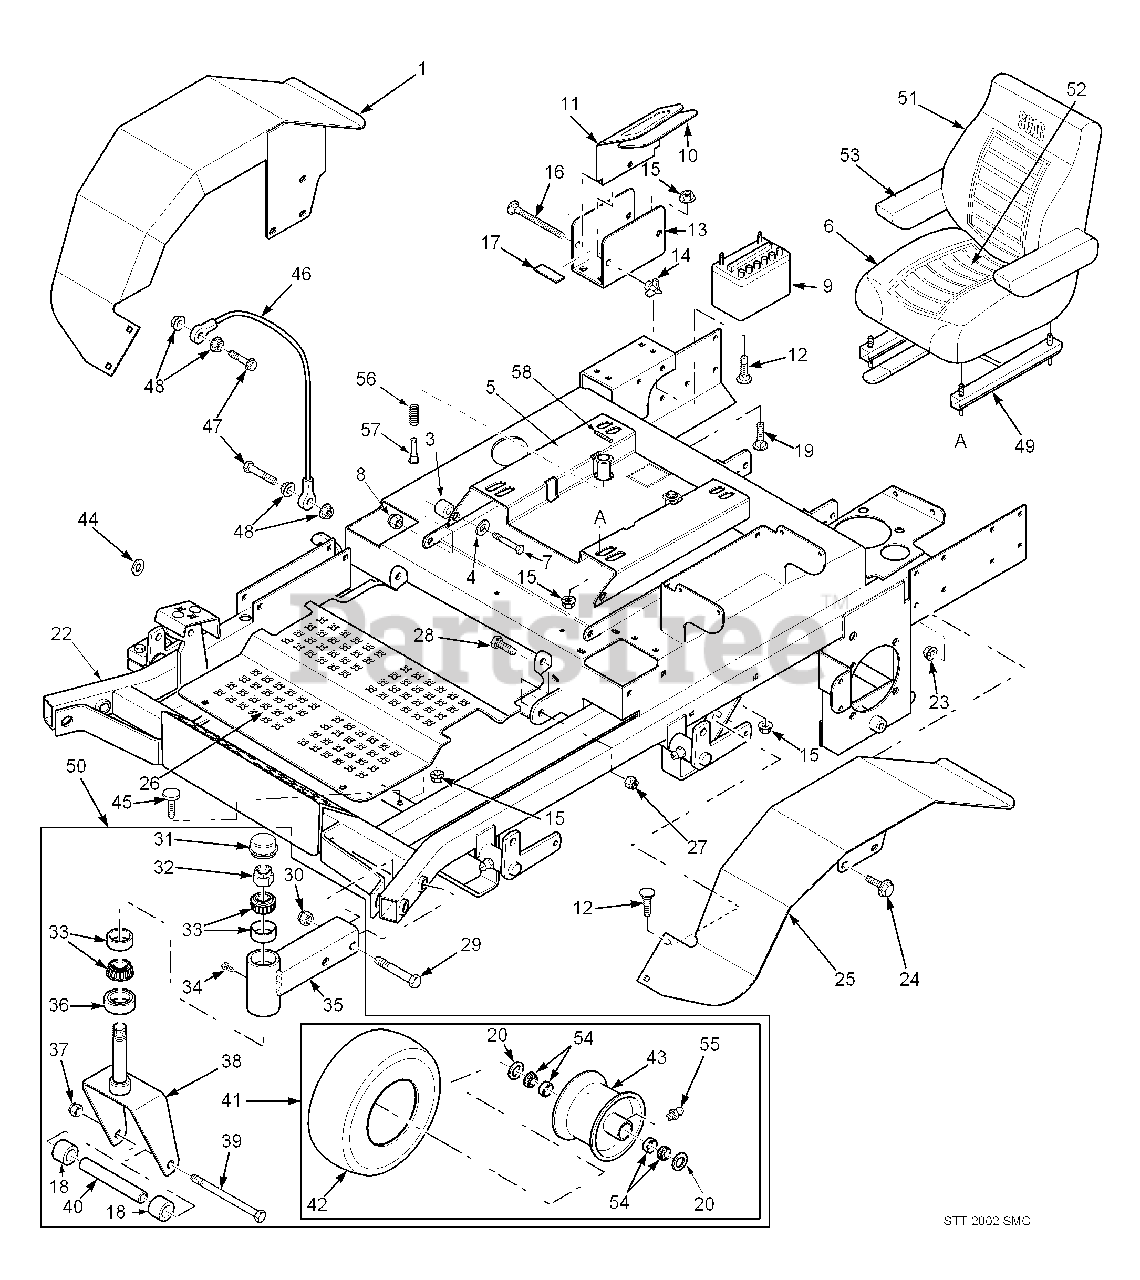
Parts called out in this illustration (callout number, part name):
1	Fender Weldment, RH
2	Bolt, Hex Head, 5/16-18 x 1, Zinc
3	Spacer
4	Flatwasher, 3/8-.391 x .938 x .105
5	Seat Plate Weldment
6	Seat Assembly w/armrest
7	Bolt, Hex Head 3/8-16 x 2.0"
8	Nut, Elastic Stop 3/8-16
9	Battery
10	Pad, Battery Cover
11	Cover, Battery
12	Bolt, Carriage 5/16-18 x 3/4"
13	Plate, Battery Box
14	Wing Nut, 1/4-20 x 3/4"
15	Nut, Hex Serrated Flange 5/16-18
16	Bolt, Carriage 1/4-20 x 6"
17	Rubber Pad
18	Spacer, Caster Wheel
19	Bolt, Carriage 5/16-18 x 1"
21	Lock Nut, 3/8-16, Elast. Stop
22	Main Frame
23	Nut, Hex Serrated Flange 3/8-16
24	Screw, Hex Serrated Flange 3/8-16 x 1"
25	Fender Weldment, LH
26	Foot Plate
27	Nut, Hex Elastic Stop 3/8-16
28	Bolt, Hex Head 3/8-16 x 1"
29	Bolt, Hex Head 5/8-11 x 4"
30	Nut, Hex Elastic Stop 5/8-11
31	Cap, Grease
32	Nut, Hex Elastic Stop 1.0-14
33	Bearing W/Race
34	Plug, 1/4-28 THD Form
35	Extention Weldment, Caster 52A & 61A
35	Extention Weldment, Caster 61A
36	Seal, 2.00 OD. x 1.625 Bore
37	Nut, Hex Elastic Stop 1/2-13
38	Yoke Weldment, Caster
39	Bolt, Hex Head 1/2-13 x 9-1/2"
40	Sleeve, Caster Wheel
41	Wheel Assy, 61A, 72A
42	Tire, 13 x 6.50 4-Ply
43	Rim Assembly, 61A & 72A
44	Flatwasher, 3/8"-.391 x .938 x .105
45	Bumper, Rubber
46	Cable, Seat Stop
47	Bolt, Hex Head 1/4-20 x 1-1/4"
48	Nut, Hex Serrated Flange 1/4-20
49	Seat Adjustment, Track Set
50	Caster Wheel Assy 61A
51	Back Cushion Cover
52	Seat Cushion Cover
53	Arm Rest, Right Hand
54	Bearing w/ Race
55	Grease Fitting
56	Spring, Seat
57	Pin Retainer, Spring
58	Roll Pin, Spring 5/32 x 3/4"
